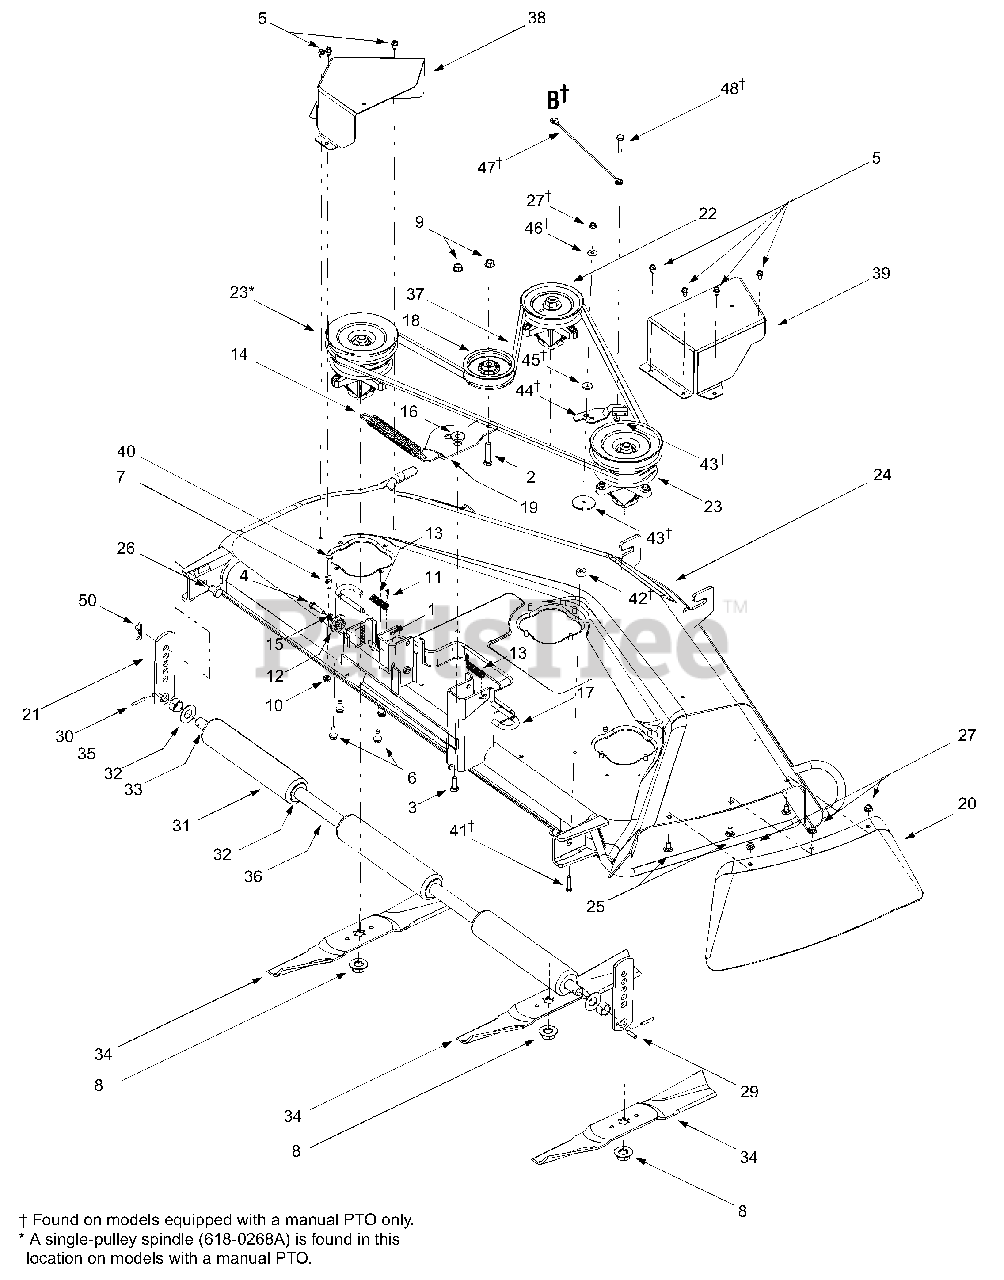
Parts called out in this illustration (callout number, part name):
1	Carriage Screw, 1/4-20 x .5
2	Hex Cap Screw, 3/8-16 x 1.75
3	Hex Cap Screw, 3/8-16 x 1.0
4	Hex Cap Screw, 5/16-18 x 1.25
5	Self Tapping Screw,1/4-20 x .5
6	Self Tapping Screw, 5/16-18 x .75
7	Center Lock Nut, 1/4-20
8	Hex Flange Nut, 5/8-18
9	Flange Lock Nut, 3/8-16
10	Hex Flange Lock Nut, 1/4-20
11	Internal Cotter Pin, .072 x 1.12
12	Deck Adjustment Gear
13	Compression Spring, .406 x .531 x 1.75
14	Extension Spring, .91 x 7.33
15	Lock Washer, 5/16
16	Shoulder Spacer, .625 x .169
17	Deck Release Pin
18	Flat Idler Pulley, 3.5 OD
22	Center Spindle Assembly, 5 Dia.
23	Double Pulley Spindle Assembly
26	Clevis Pin, .50 Dia. x .78
27	Hex Flange Lock Nut, 5/16-18 (Grade 5)
29	Spring Pin, 1/4 Dia. x 1
30	Spring Pin, 3/16 x 1.25
31	Deck Roller
32	Flat Washer, .78 x 1.59 x .06
33	Deck Roller Shaft, .75 Dia. x 47.12
34	Blade, Star Center, 17.3
35	Spacer, .752 x 1.0 x .53
41	Hex Cap Screw, 5/16-18 x 1.5
42	Spacer, .34 x .87 x .44
43	Flat Washer, .34 x 2.5 x .10
44	Deck Brake Assembly
45	Shoulder Spacer
46	Bell Washer, .325 x .930 x .045
47	Bracket Cable, 12"
48	Shoulder Screw, .374 x 1.16
